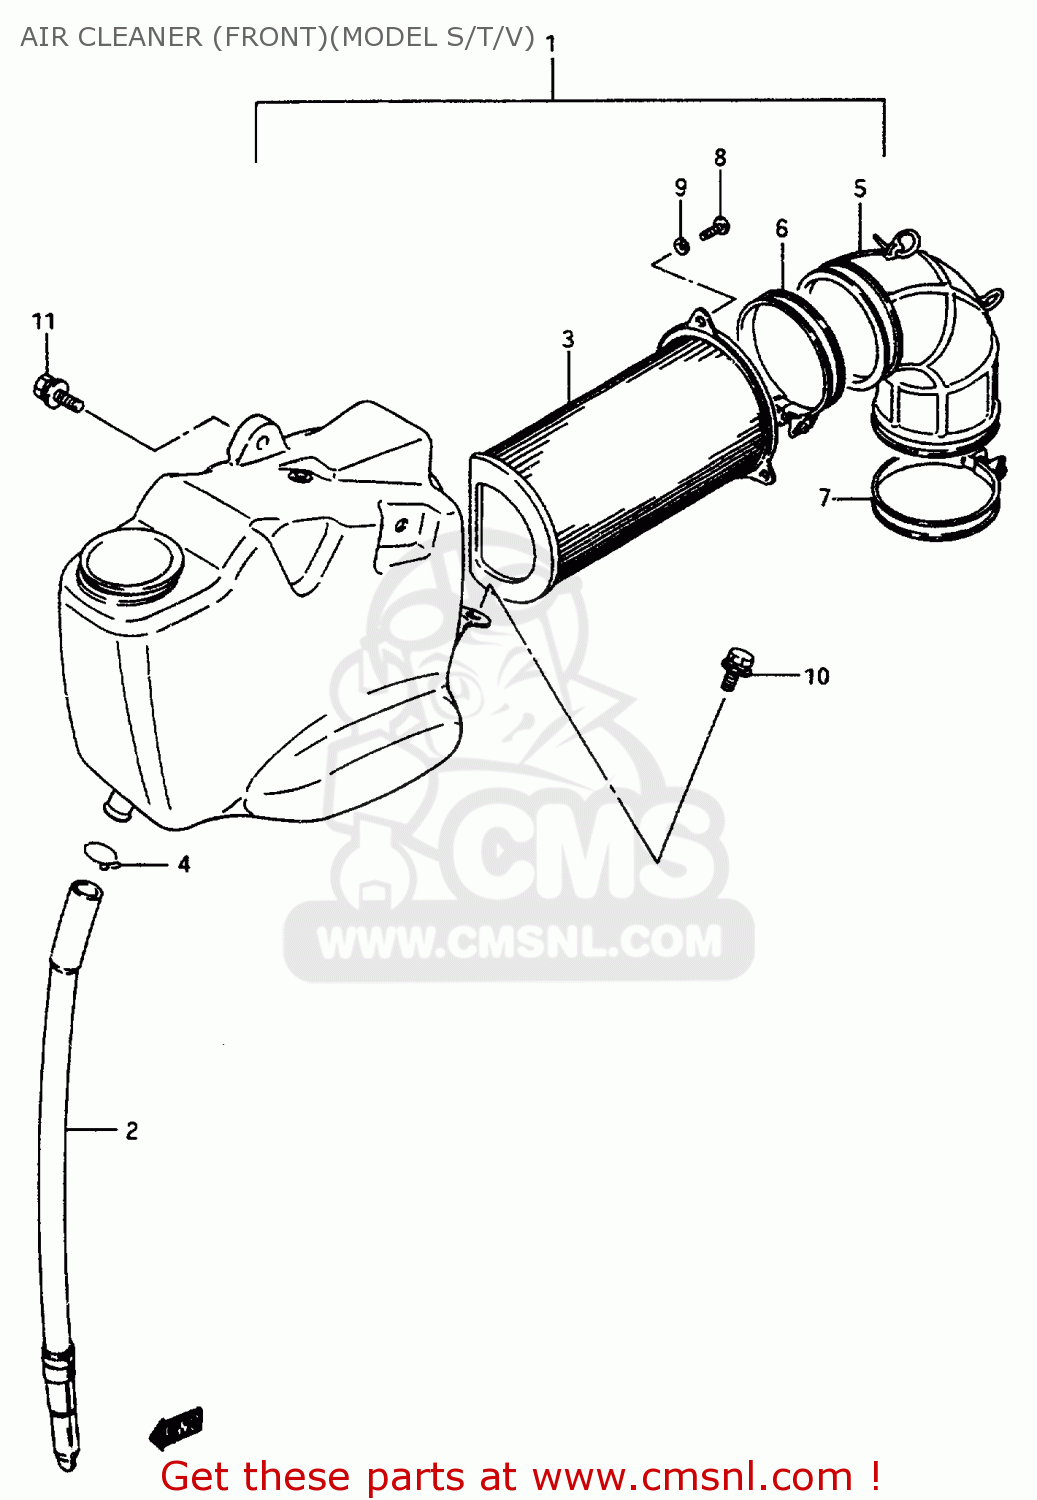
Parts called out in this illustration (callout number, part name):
1	CLEANER ASSY,AIR FR
2	TUBE,DRAIN
3	FILTER ASSY
4	CLIP
5	TUBE,AIR CLEANER OUTLET
6	CLAMP
7	CLAMP
8	SCREW
9	WASHER,LOCK
10	BOLT
11	BOLT
12	WASHER,LOCK
13	WASHER
